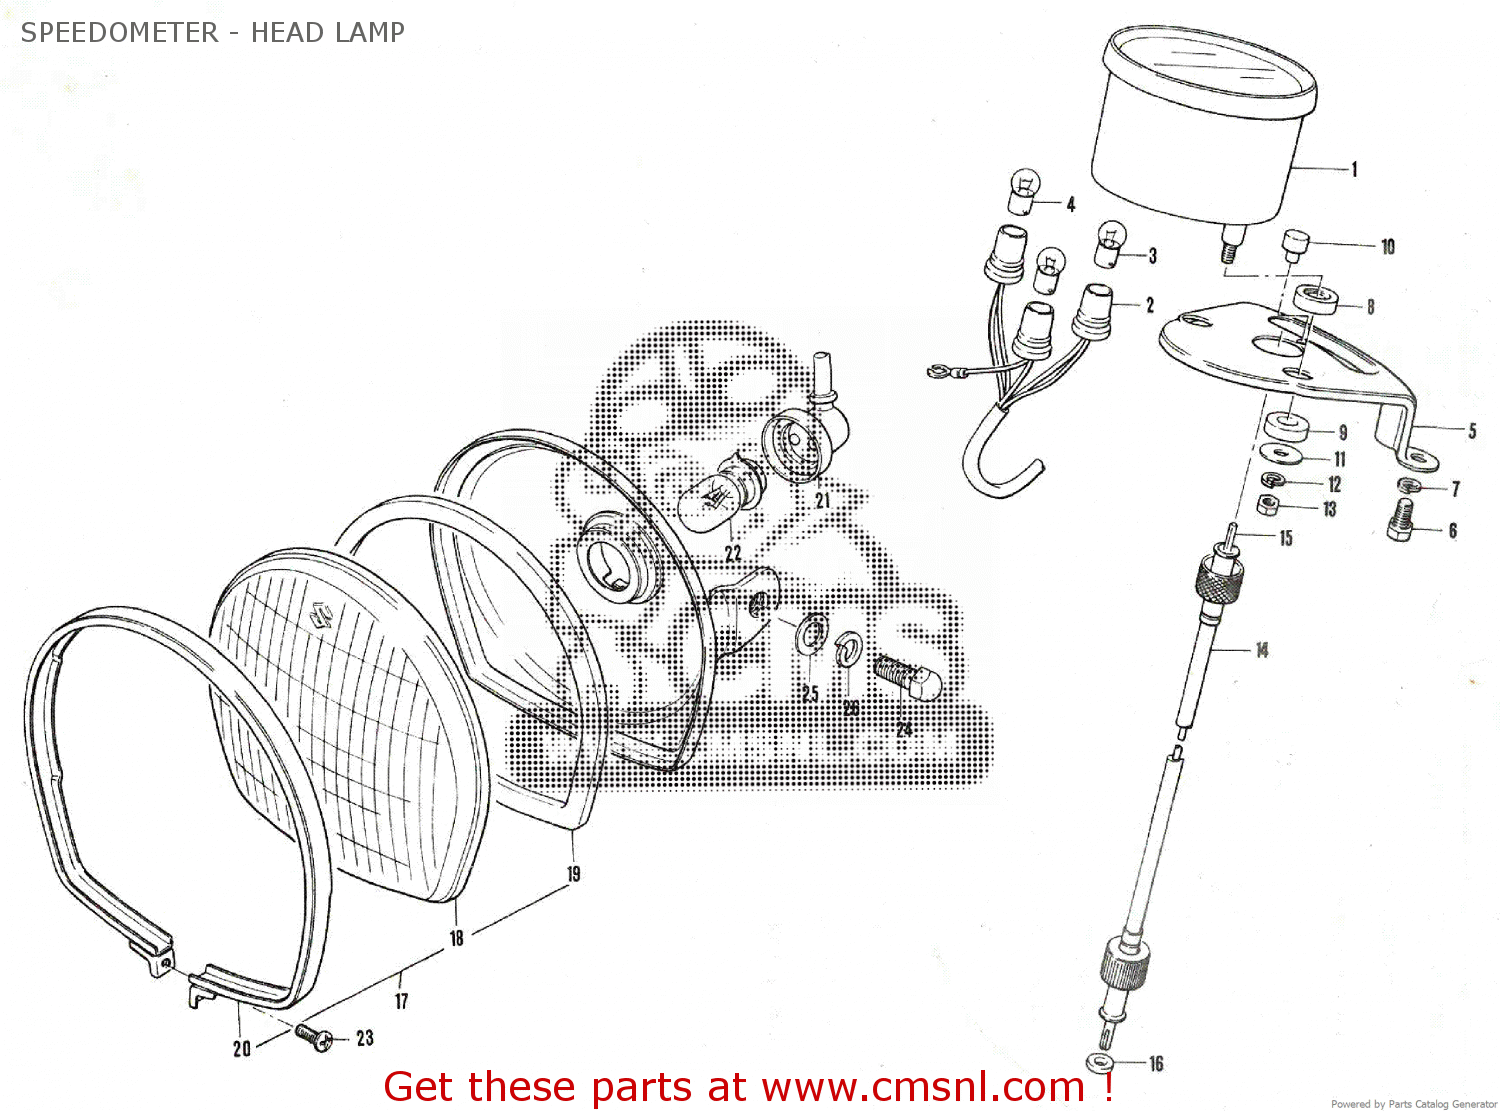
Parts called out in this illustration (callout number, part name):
1	SPEEDOMETER ASS'Y
2	SOCKET,METER
3	BULB(6V/3W)
4	BULB(6V1.7W,STANLEY,A61A)
5	BRACKET,METER
6	HEXAGON BOLT
7	LOCK WASHER
8	CUSHION,METER
9	CUSHION
10	CUSHION,METER
11	WASHER (5.5X18X1.6)
12	LOCK WASHER
13	NUT
14	CABLE ASSEMBLY,SPEEDOMETER
15	CABLE ASSEMBLY,SPEEDOMETER
16	SEAL,OIL METER CABLE
17	HEAD LAMP ASS'Y
18	LENS,HEADLAMP
19	COVER,SOCKET
20	RETAINER,HEADLAMP
21	HEAD LAMP SOCKET
22	BULB
23	SCREW
24	BOLT
25	WASHER
26	LOCK WASHER
